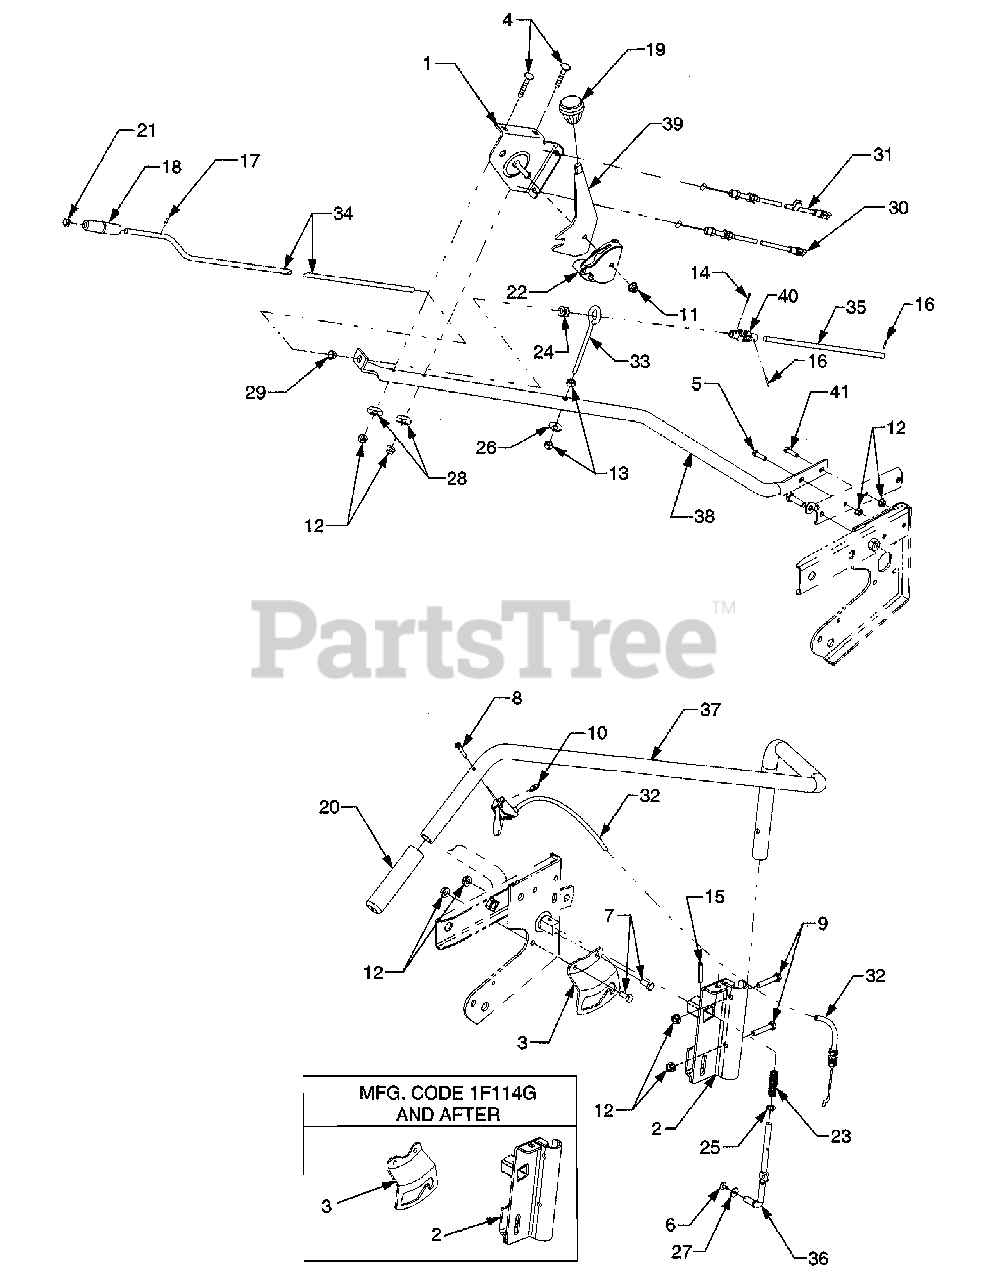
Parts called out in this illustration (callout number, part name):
1	Bracket, Chute Tilt
2	Bracket, Lift Mfg. Code 1F104G & Before
2	Bracket, Lift Mfg. Code 1F114G & After
3	Bracket, Lift Handle Latch. Mfg. Code 1F104F & Before
3	Bracket, Lift Handle Lockout. Mfg. Code 1F114G & After
4	Bolt, Carriage 5/16-18 x 1.5 GR2
5	Screw, Hex Cap 5/16-18 x 1.5 GR5
6	Screw, Hex Wash, Hd Tapp #10-16 x .375
7	Screw, Hex Cap 5/16-16 x .75 GR5
8	Screw, Pan Phillips Hd. 10-24 x 1.5
9	Screw, Hex Cap 5/16-18 x 1.75 GR5
10	Nut, Flat Weld, 10-24
11	Nut, Hex Insert Flange Lock 5/16-18
12	Nut, Hex Flange Lock, 5/16-18 GR5
13	Nut. Hex. 5/16-18 GR5
14	Pin. Cotter. 3/32 x . 75
15	Pin. Spirol. 1/4 x 1-1/2
16	Pin. Sprol. . 125 x . 812
17	Pin. Roll. 1/8 x . 63
18	Knob. Chute Crank
19	Knob. Tilt Handle
20	Grip. Lift Handle
21	Cap. Push
22	Guide. Cable
23	Spring. Compression
24	Grommet. Rubber
25	Washer. Flat. .38 x . 62 x . 063
26	Washer. Bell. .34 x . 872 x . 06
27	Washer. Flat. .19 x . 62 x . 063
28	Washer. Saddle. .32 x . 93
29	Bushing. Plastic
30	Cable. Chute Control
31	Cable. Chute Control w/Clip
32	Cable/Trigger Assembly, Lift Latch (Replaces 746-3060A)
33	Eyebolt. Chute Crank
34	Rod. Chute Crank. 28.0 in . Lg
35	Rod. 1 1.375 Lg
36	Rod. Lift Index
37	Handle. Lift Replaces 750-1028A
38	Tube. Chute Crank Support
39	Handle. Chute Tilt
40	Block Assembly. Joint
41	Screw. Hex Cap 5/16-18 x 1.25 GR5
